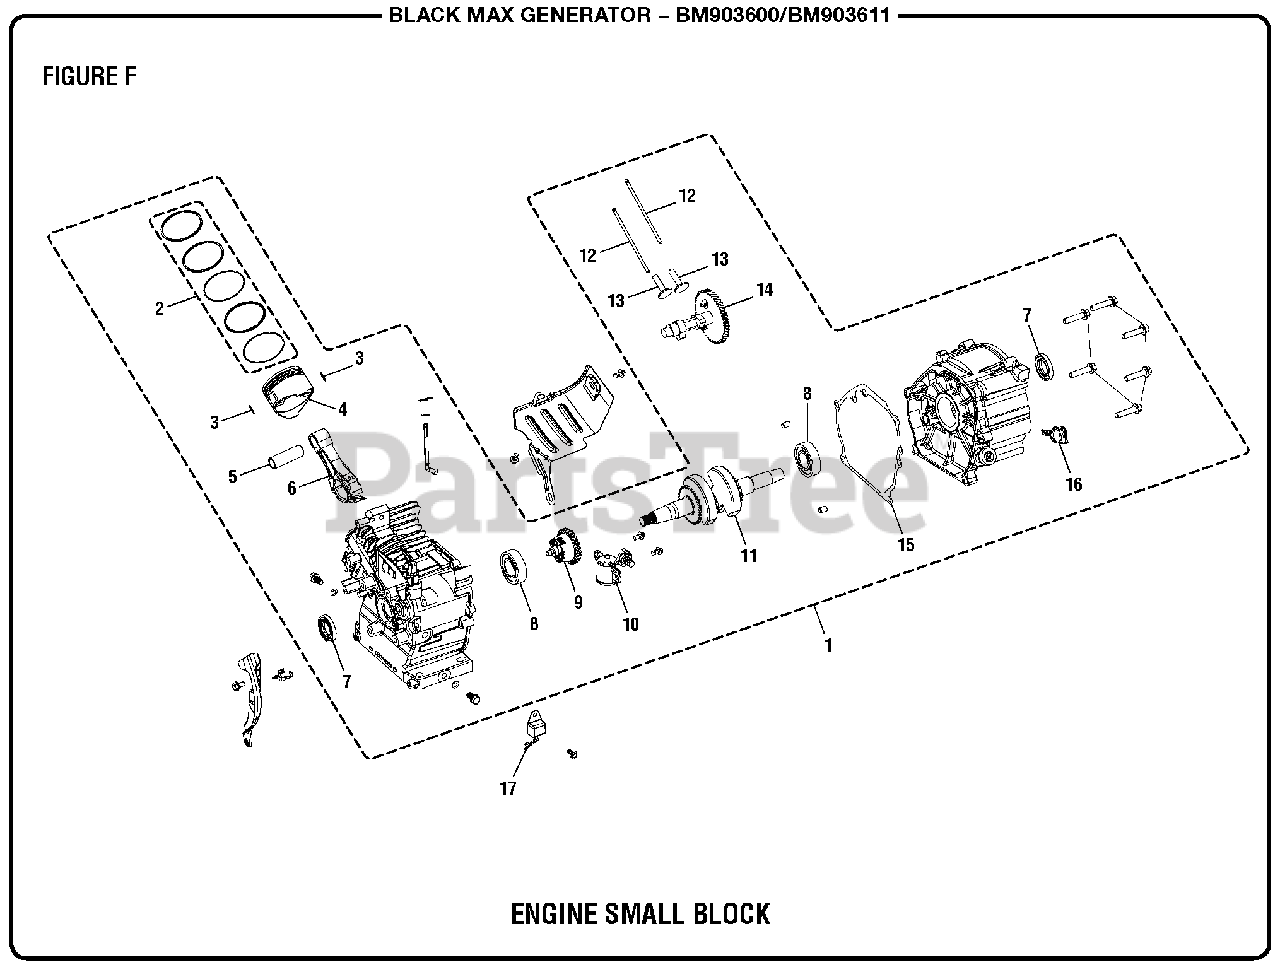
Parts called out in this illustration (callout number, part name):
1	Engine Small Block
2	Piston Ring Set
3	Piston Clip
4	Piston
5	Piston Pin
6	Connecting Rod Assembly
7	Oil Seal
8	Ball Bearing
9	Governor Assembly
10	Switch Assembly (Oil Level)
11	Crankshaft Assembly
12	Valve Lifter Assembly
13	Valve Tappet
14	Camshaft Assembly
15	Casecover Gasket
16	Dipstick
17	Amplifier
